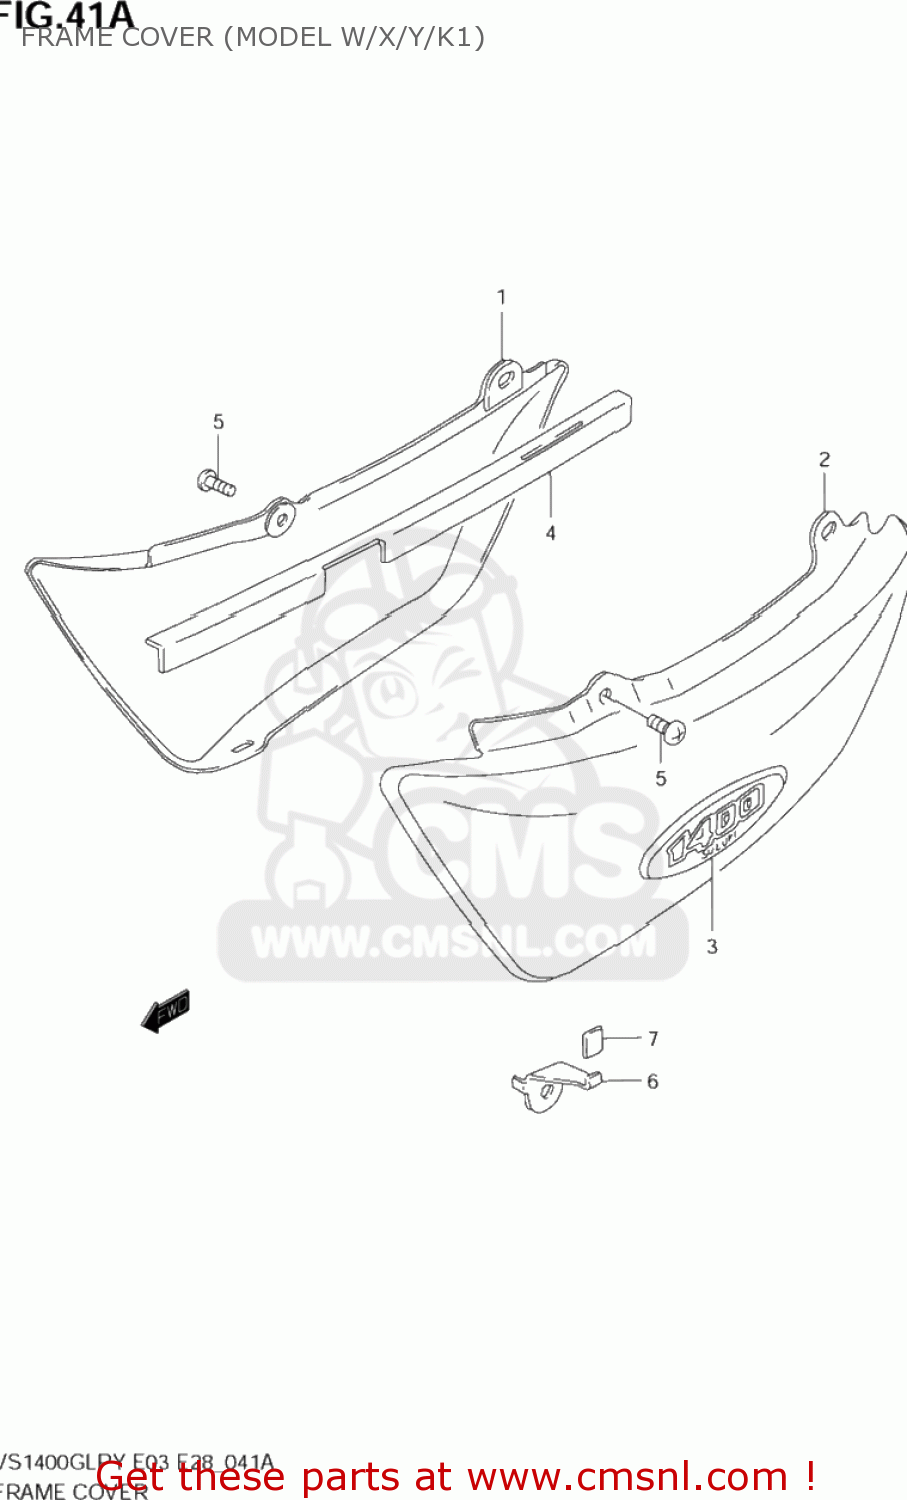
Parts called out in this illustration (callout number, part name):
1	1-2
2	COVER,FRAME,L(BLUE)
3	EMBLEM,FRAME COVER
4	PROTECTOR,FRAME COVER,R
5	SCREW 6X12
6	HOOK,FRAME COVER,L
7	CUSHION,FRAME COVER HOOK
